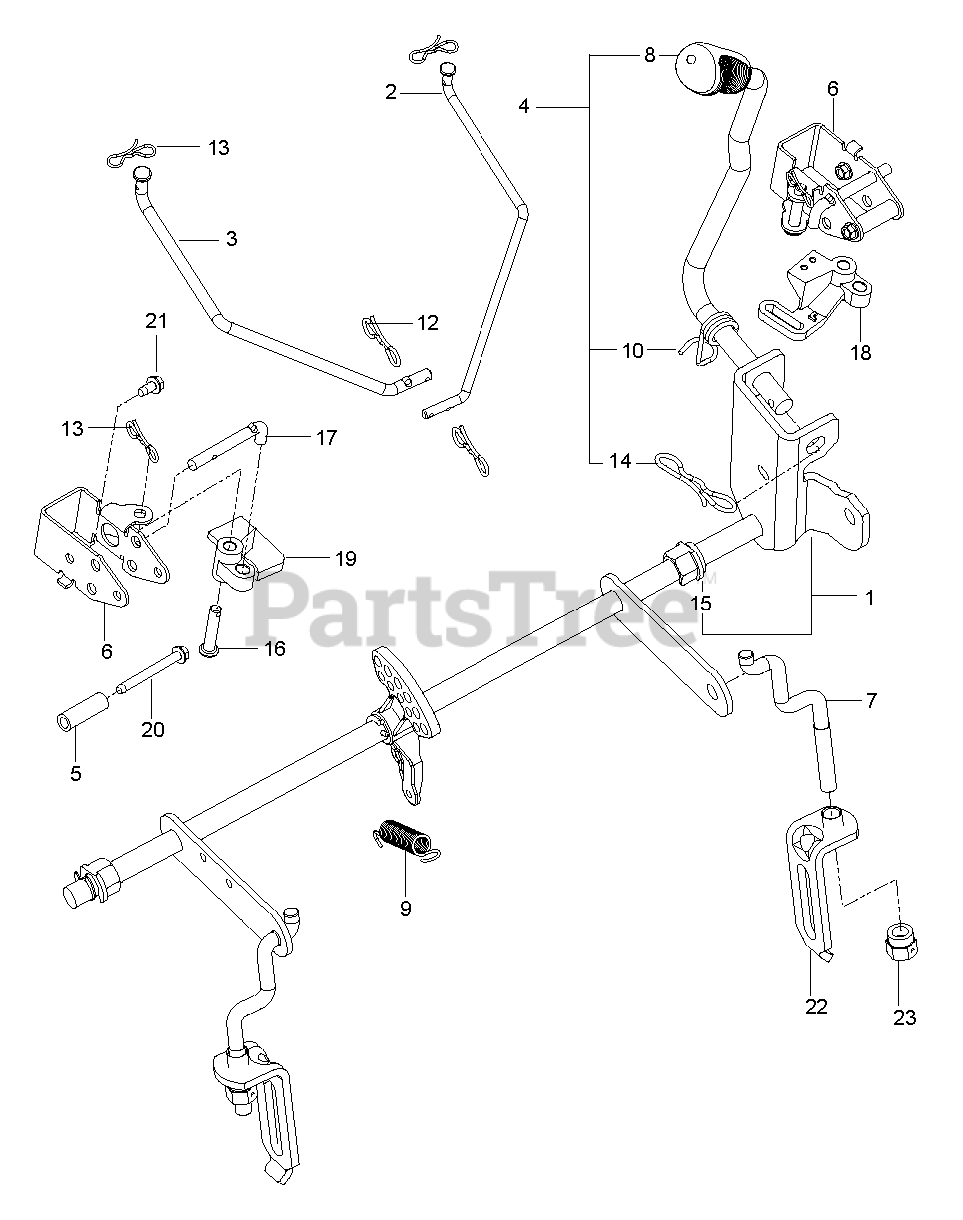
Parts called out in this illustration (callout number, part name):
1	SHAFT ASSY DECK LIFT WELDMENT
2	LINK.BRAKE.PARK.UPPER.LH
3	LINK.BRAKE.PARK.UPPER.RH
4	LIFT.LEVER.ASM.RZ.SERVICE
5	SPACER.334.ID.5.OD.1.5.L
6	BRACKET.BELLCRANK.PBRAKE X431
7	LINK, REAR SUSPENSION
8	GRIP.HANDLE.LIFT.PVC.BLACK
9	RETURN.BRAKE.PARK.AUTO
10	SPRING.TORSION.LIFT.HANDLE
12	PIN.COTTER.5/16.BOW TI
13	PIN COTTER;LOCKING;BOWTIE;1IN
14	PIN.COTTER.7/16.BOW TI.
15	PLASTIC NUT
16	PIN.5.16X1.5
17	ROD.PUSH.BRAKE
18	BELLCRANK.LH
19	BELLCRANK.RH
20	SCREW THD;ROLL;1/4-20 X 2.25
21	SCREW.1/4-20X5/8
22	BRACKET CONNECT LINK LIFT
23	BUSHING ALIGNMENT LINK LIFT
